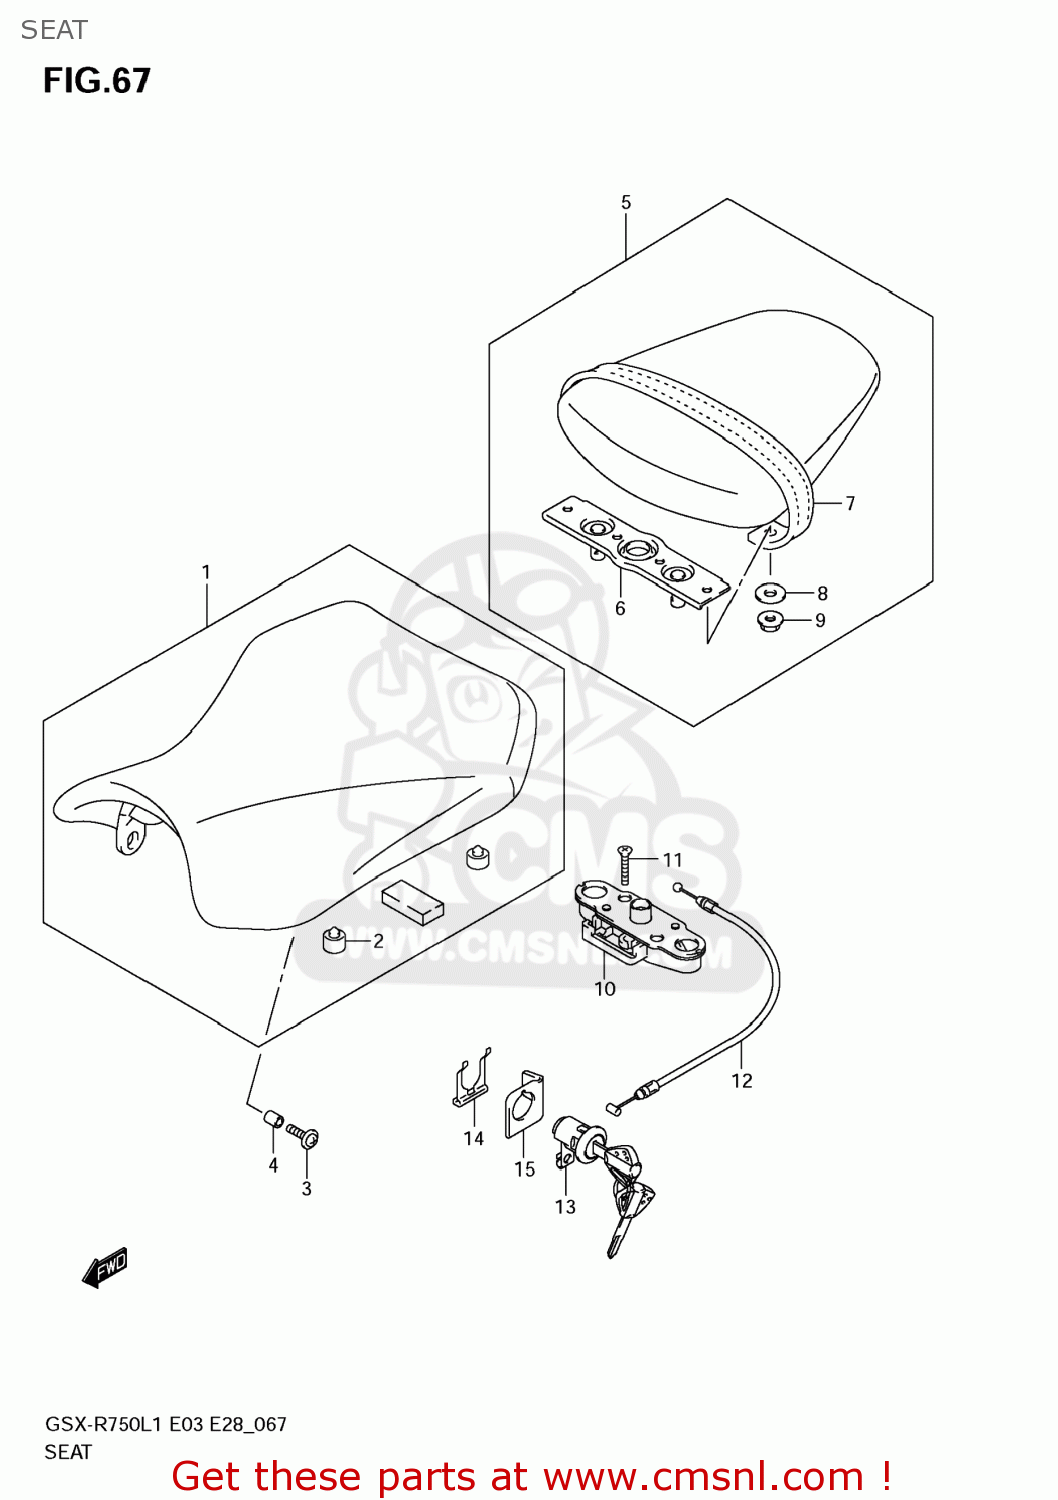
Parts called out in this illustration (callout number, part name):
1	SEAT ASSY
2	CUSHION
3	SCREW(6X25)
4	SPACER(6.5X9X10.5)
5	SEAT ASSY.PILLI
6	STRIKER
7	BAND ASSY,SEAT
8	WASHER(6.5X20X1.6)
9	NUT
10	BRACKET,SEAT SUPPORT
11	SCREW
12	CABLE,SEAT LOCK
13	LOCK SET,SEAT
14	PLATE,SEAT LOCK ASSY
15	GUIDE,SEAT LOCK CABLE
